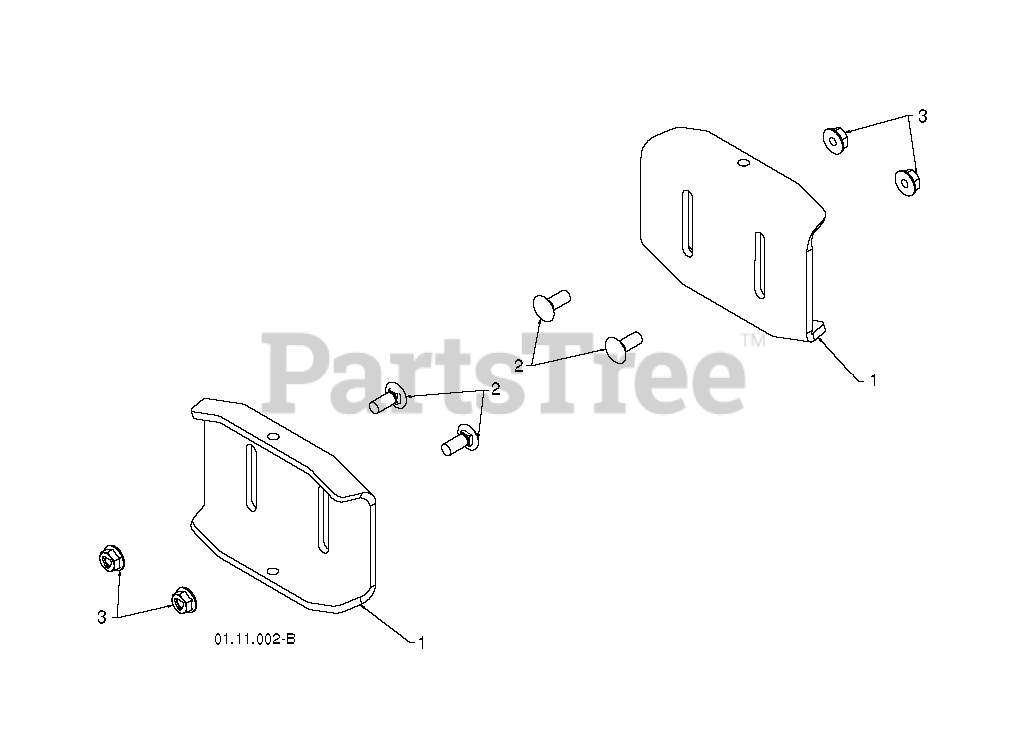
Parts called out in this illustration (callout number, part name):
1	PLATE.SKID.HEAVYDUTY.BLACK
2	BOLT
3	NUT.LOCK.5/16-18
